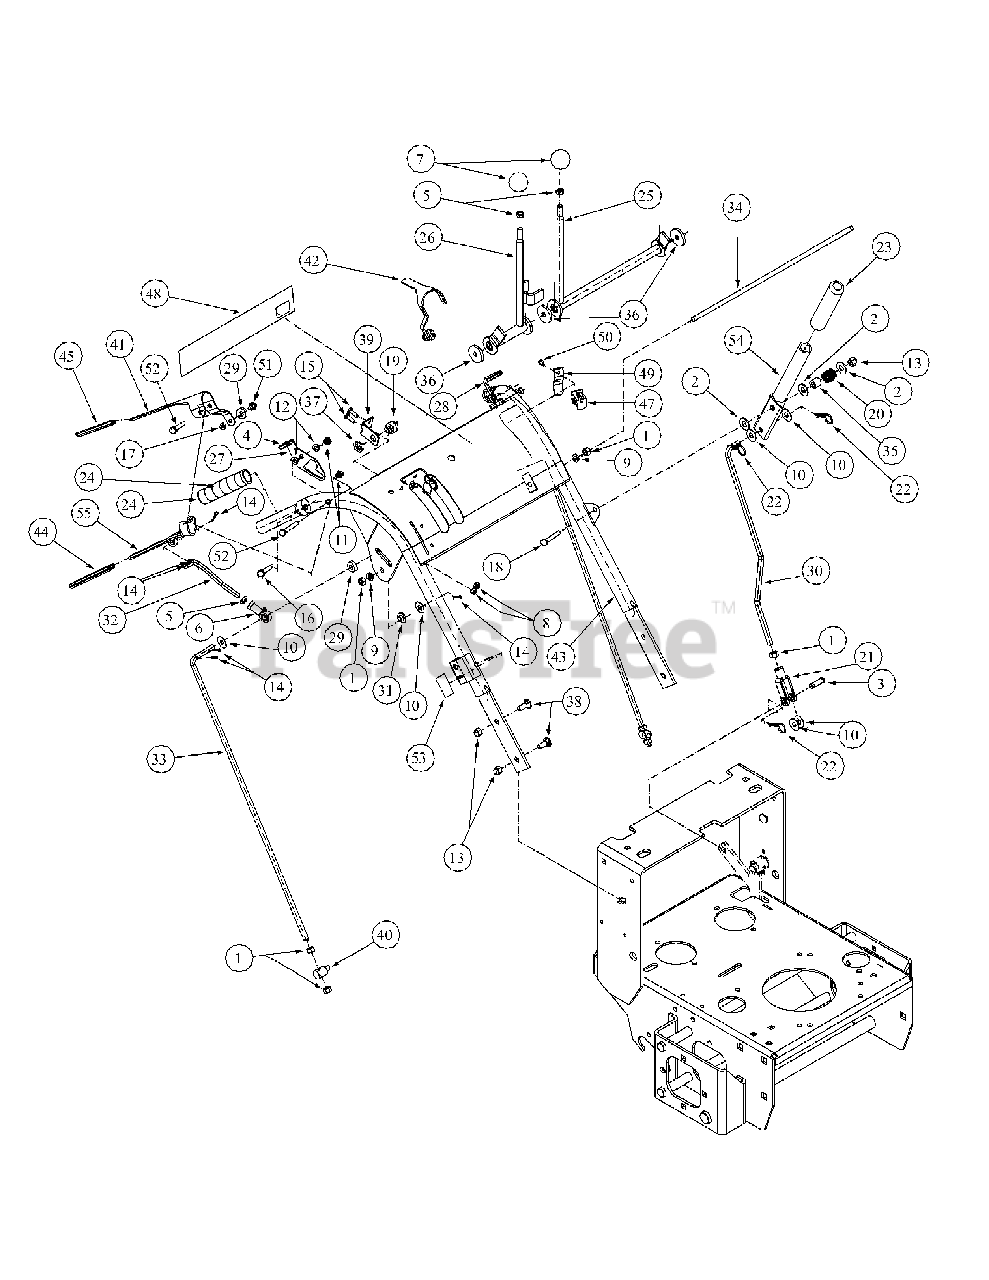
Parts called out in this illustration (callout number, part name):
1	Hex Nut, 3/8 - 16
2	Flat Washer, SS, 3/8
3	Clevis Pin, 3/8 x 1 1/8
4	Grip, 1.25, Black Neutral Lock
5	Hex Nut, Jam, 3/8-24
6	End Rod, 3/8
7	Knob, 1-3/8 x 1-19/64, 3/8-24
8	Lock Nut, Nylon Insert, 1/4-20
9	Lock Washer, 3/8 Zinc
10	Flat Washer, 3/8, SAE
11	Nut, 5/16-18
12	Flat Washer, SAE 5/16
13	Lock Nut, Nylon Insert, 3/8-16
14	Cotter Pin, 5/32 x 1-1/2 Zinc
15	HHCS, 1/4-20, .75
16	HHCS, Standard, 5/16-18 x 2
17	Lock Nut, Nylon Insert, 1/4 - 28
18	Carriage Bolt, 3/8 -16 x 2
19	Switch Operator's Presence
20	Spring, .850
21	Yoke, 3/8 - 16, Female
22	Hair Pin, 3/8 - 1/2
23	1" Grip, Black Handle
24	4-5/8" Grip, Black Plastic Handle
25	Control Assembly, Speed Hydro, LH
26	Control Assembly, Speed Hydro, RH
27	Latch, RH, Neutral Hydro
28	Latch, LH, Neutral Hydro
29	Hydro, Spacer Control Rod
30	Blade Clutch, Hydro Rod Base
31	Hydro Bush Control Rod
32	Control Rod, Short Hydro
33	Control Rod, Long Hydro
34	Hydro Rod, Speed Control
35	Sleeve Spring, 32/36/48
36	Friction Washer
37	Hex Nut, Dead Man Switch
38	Carriage Bolt, 3/8 -16 x 2
39	Mounting Switch, Neutral, Safety
40	Pivot, Belt Tightener
41	Operator Presence Control Handle, RH
42	Operator Presence Control Handle, LH
43	Hydro, Handle Assembly
44	Control Sleeve, Drive Black
45	Operators Control Sleeve, Yellow
46	Harness Adapter Assembly
47	Snap Mounting Switch
48	Handle Label
49	Retension Spring
50	Screw, TT, 10-24, .5
51	Shoulder Screw, .38 x .412, 1/4-28
52	HHCS, 5/16-18, 2.00
53	Parking Brake Decal
54	Blade Clutch Lever
55	Lever Assembly Control
